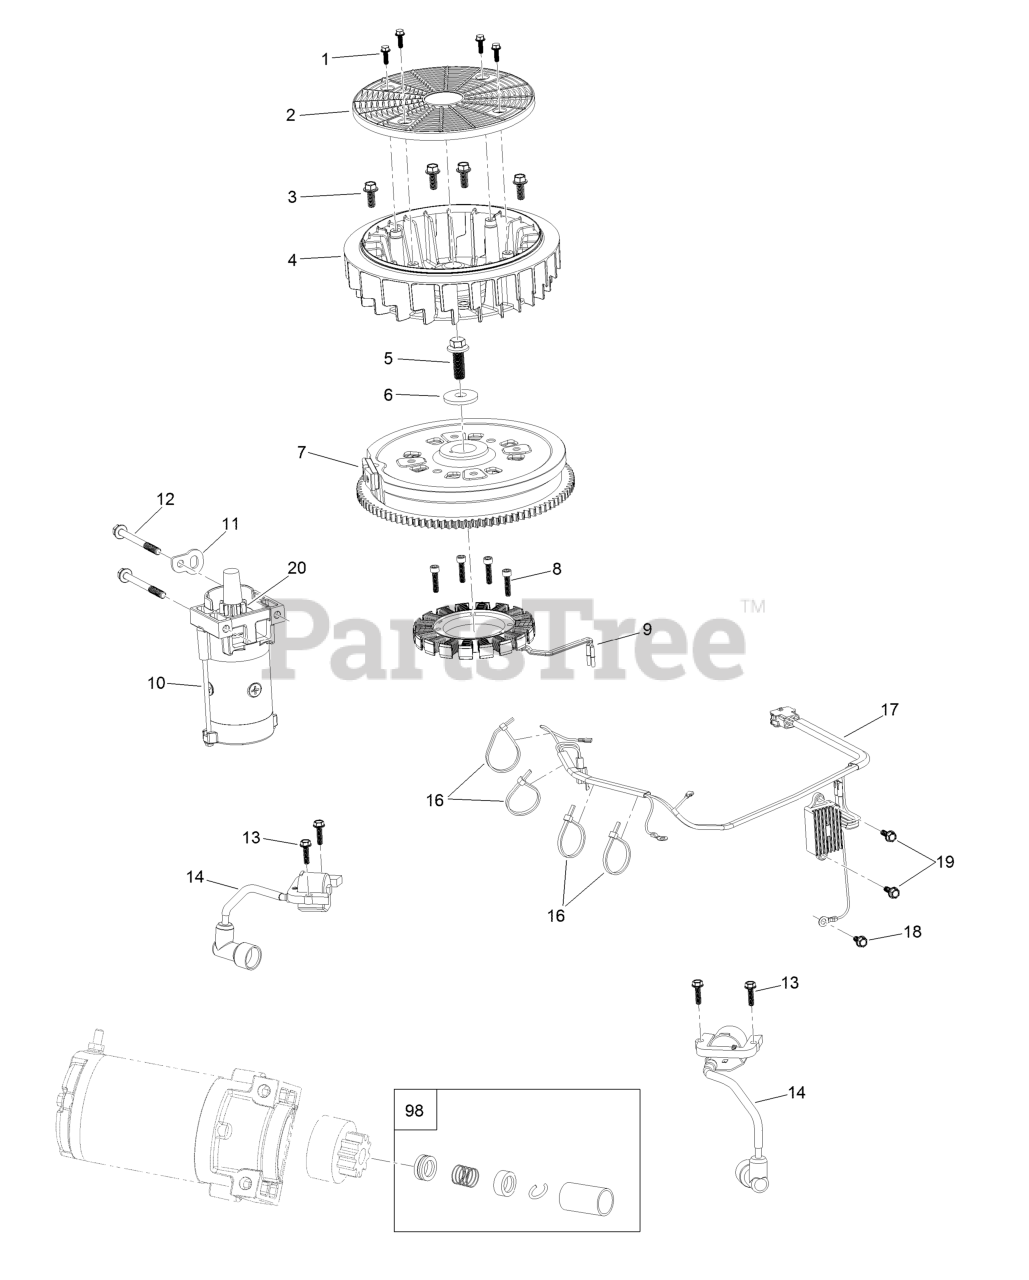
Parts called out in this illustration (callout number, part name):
1	SCREW-HWH
2	SCREEN-ROTATING
3	SCREW-HWH
4	FAN-COOLING
5	SCREW-HWH
6	WASHER-FLAT
7	FLYWHEEL
8	SCREW-HSH
11	BRACKET-LIFT
12	SCREW-HHF
13	BOLT-FLANGE
16	TIE-ZIP
17	REGULATOR-VOLTAGE W/HARNE
18	SCREW-HHF
19	SCREW-HHF
20	PINION-STARTER
98	STARTER REPAIR KIT
